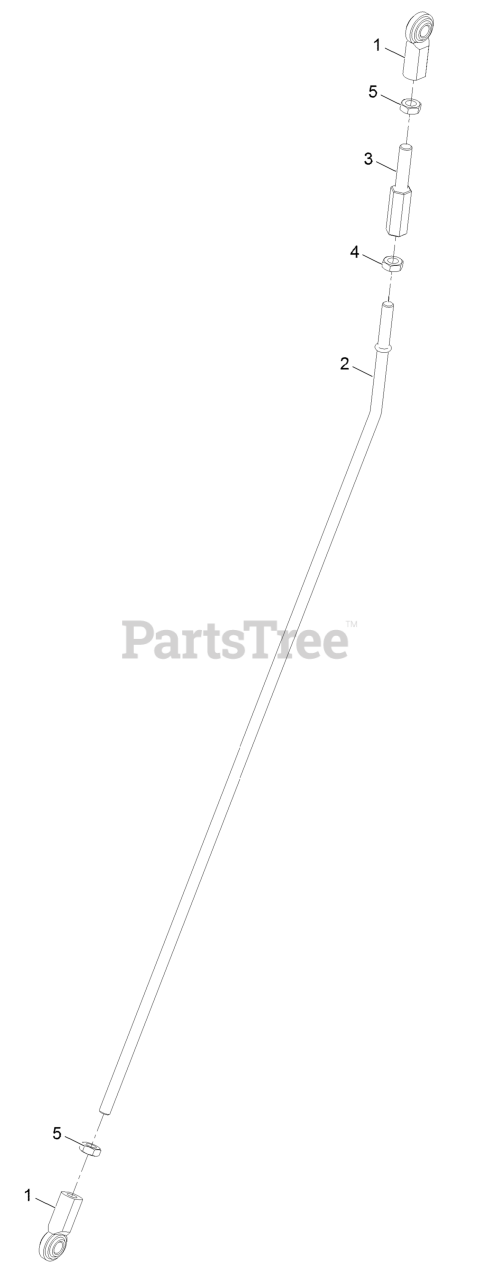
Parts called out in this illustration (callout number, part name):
1	Balljoint
2	Linkage-Motion
3	Rod-Adjustment
4	Nut-Jam 3/8-24 LH
5	Nut-Jam 3/8-24
